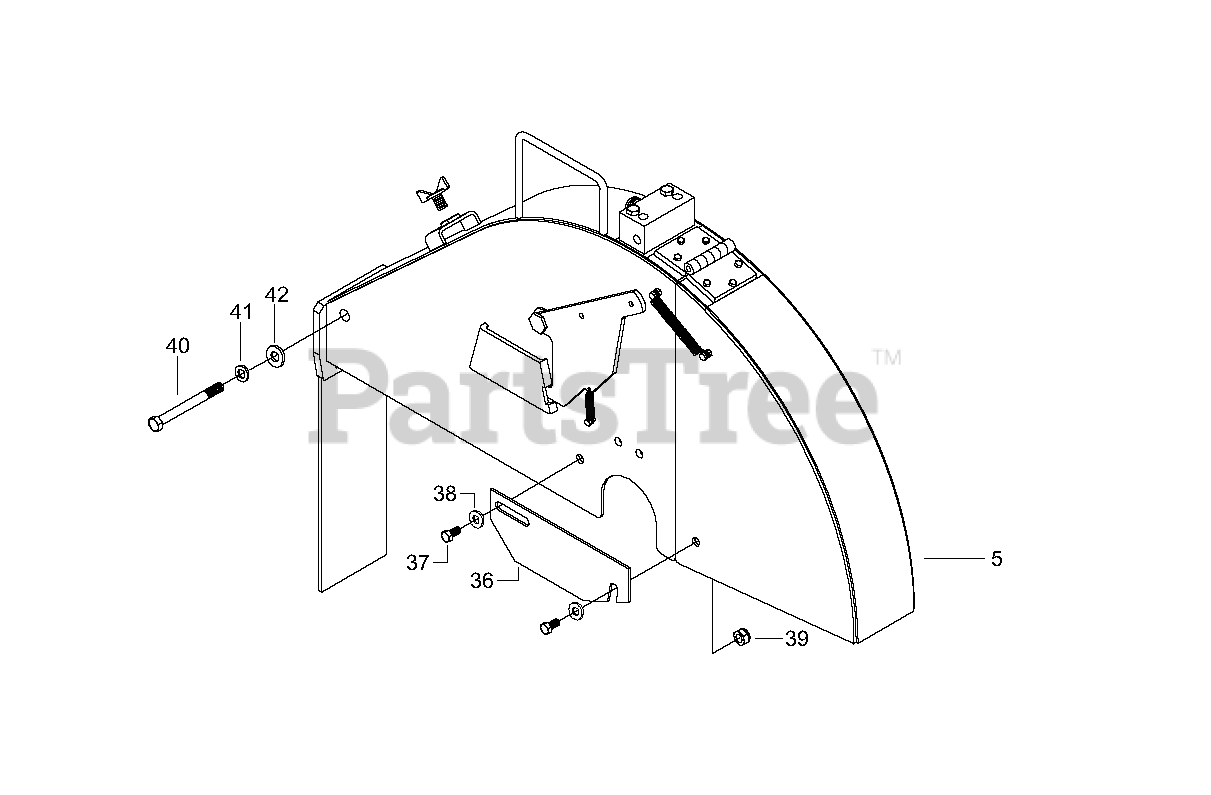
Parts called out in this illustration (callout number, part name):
37	HHCS. M12 x 1.75 x 25 DIN933ZP
38	LOCKNUT. FIBER M12 DIN 985 Z/P
40	HHCS M16 x 2.0 x 110 DIN931 ZP
